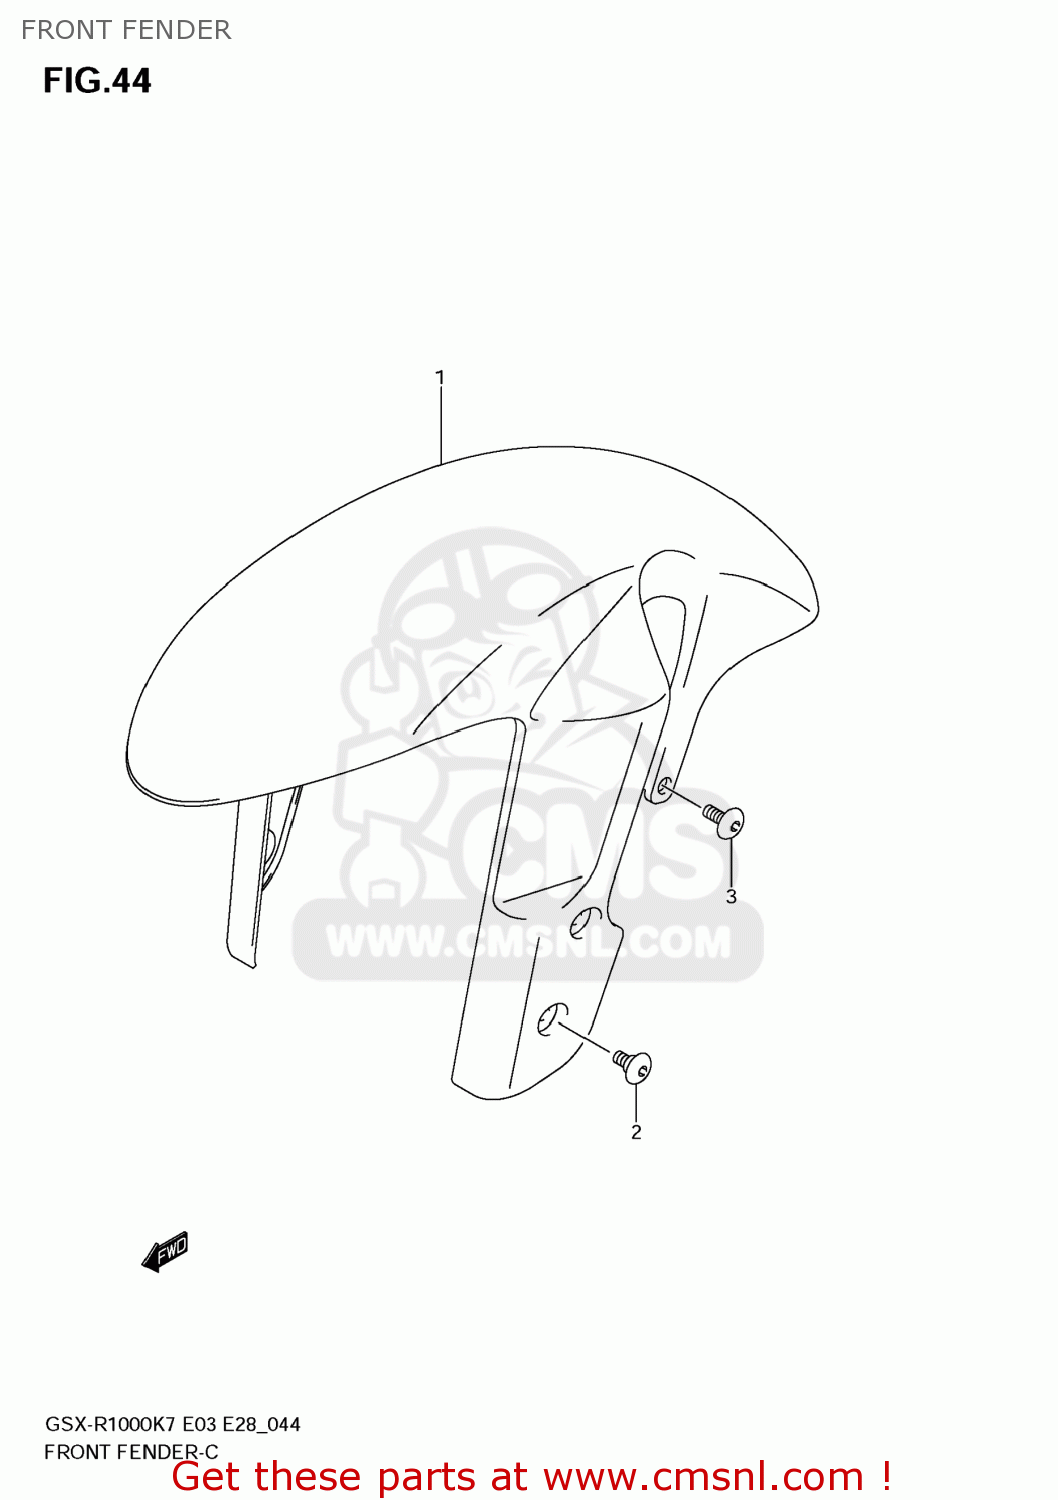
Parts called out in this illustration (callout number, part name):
1	FENDER ASSY,FR(BLACK)
2	SCREW(6X12)
3	SCREW(6X16)
